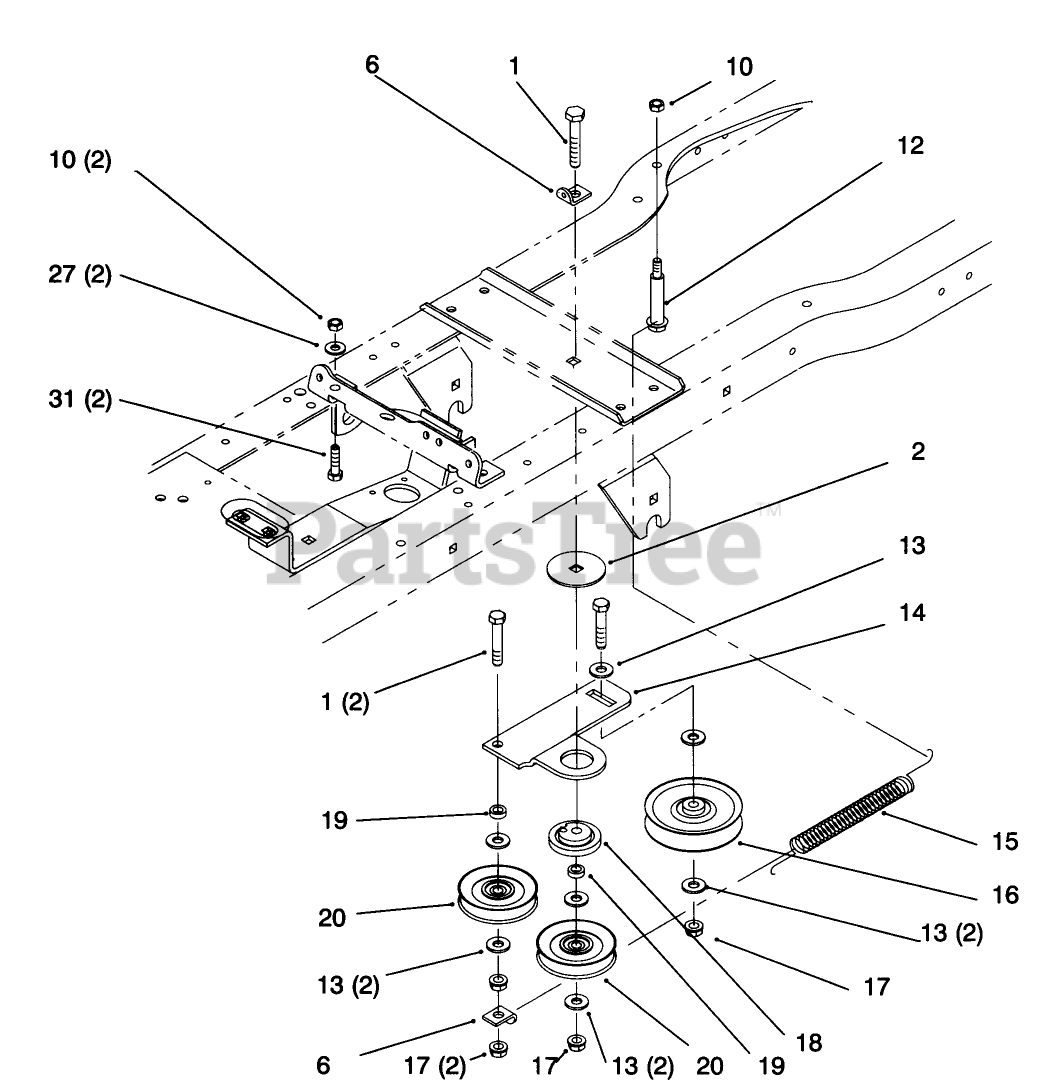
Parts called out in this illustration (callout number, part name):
1	SCREW-HH
2	WASHER-BEARING
6	CLIP - SPRING
10	NUT-LOCK, NI
12	BOLT-SHOULDER
13	WASHER-FLAT
14	ARM - IDLER
15	SPRING - CLUTCH
16	PULLEY-IDLER, FLAT
18	BUSHING
19	SPACER
20	PULLEY-IDLER
27	WASHER-PLAIN
31	SCREW-HH
